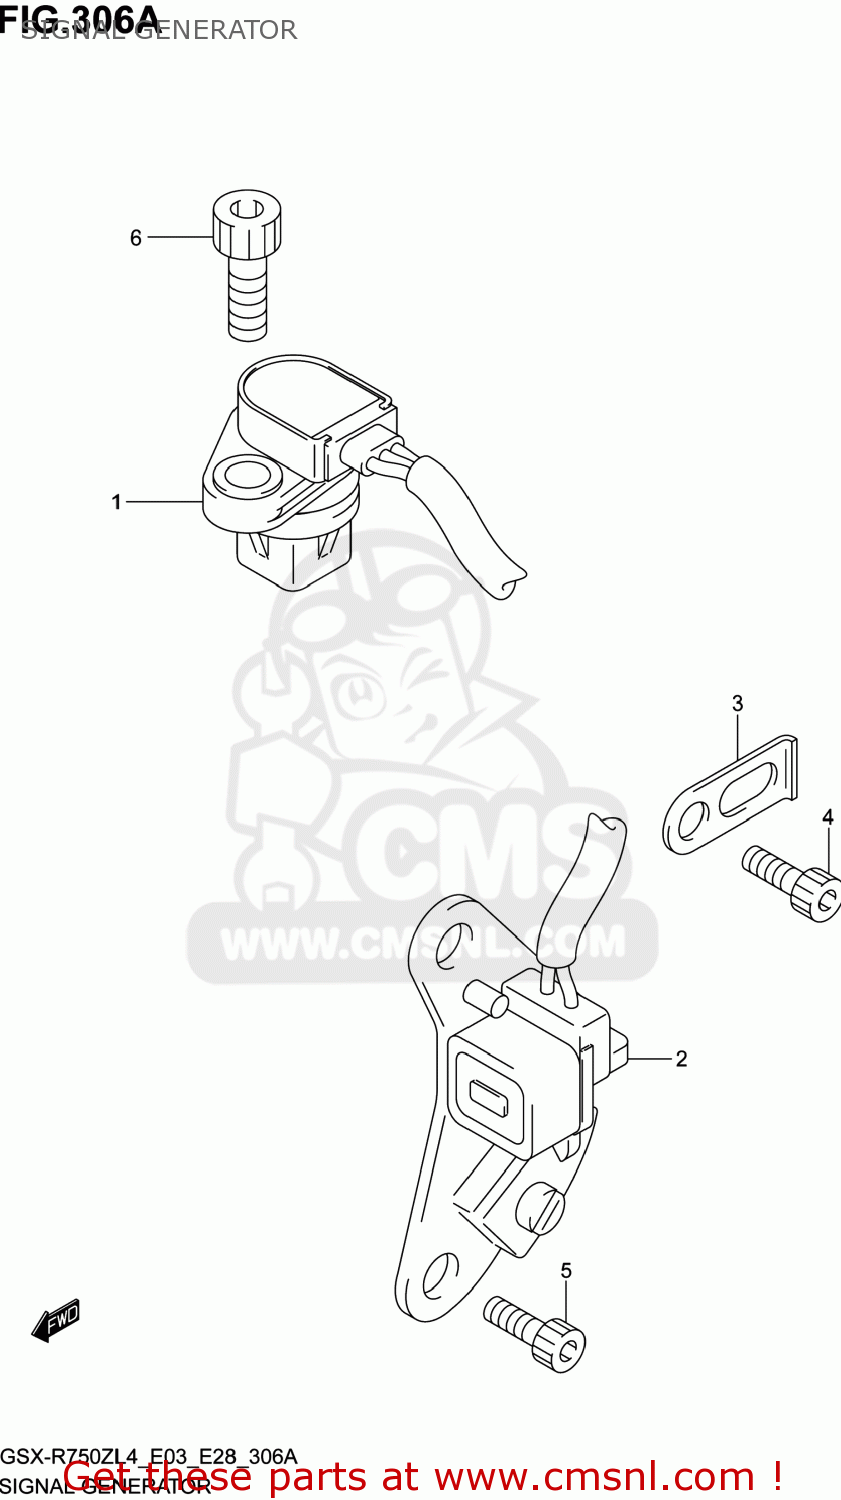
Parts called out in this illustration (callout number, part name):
1	SENSOR ASSY,CAM POSITION
2	STARTER,SIGNAL GENERATOR
3	CLAMP,SIGNAL GENERATORERATOR
4	BOLT
5	BOLT
6	BOLT
